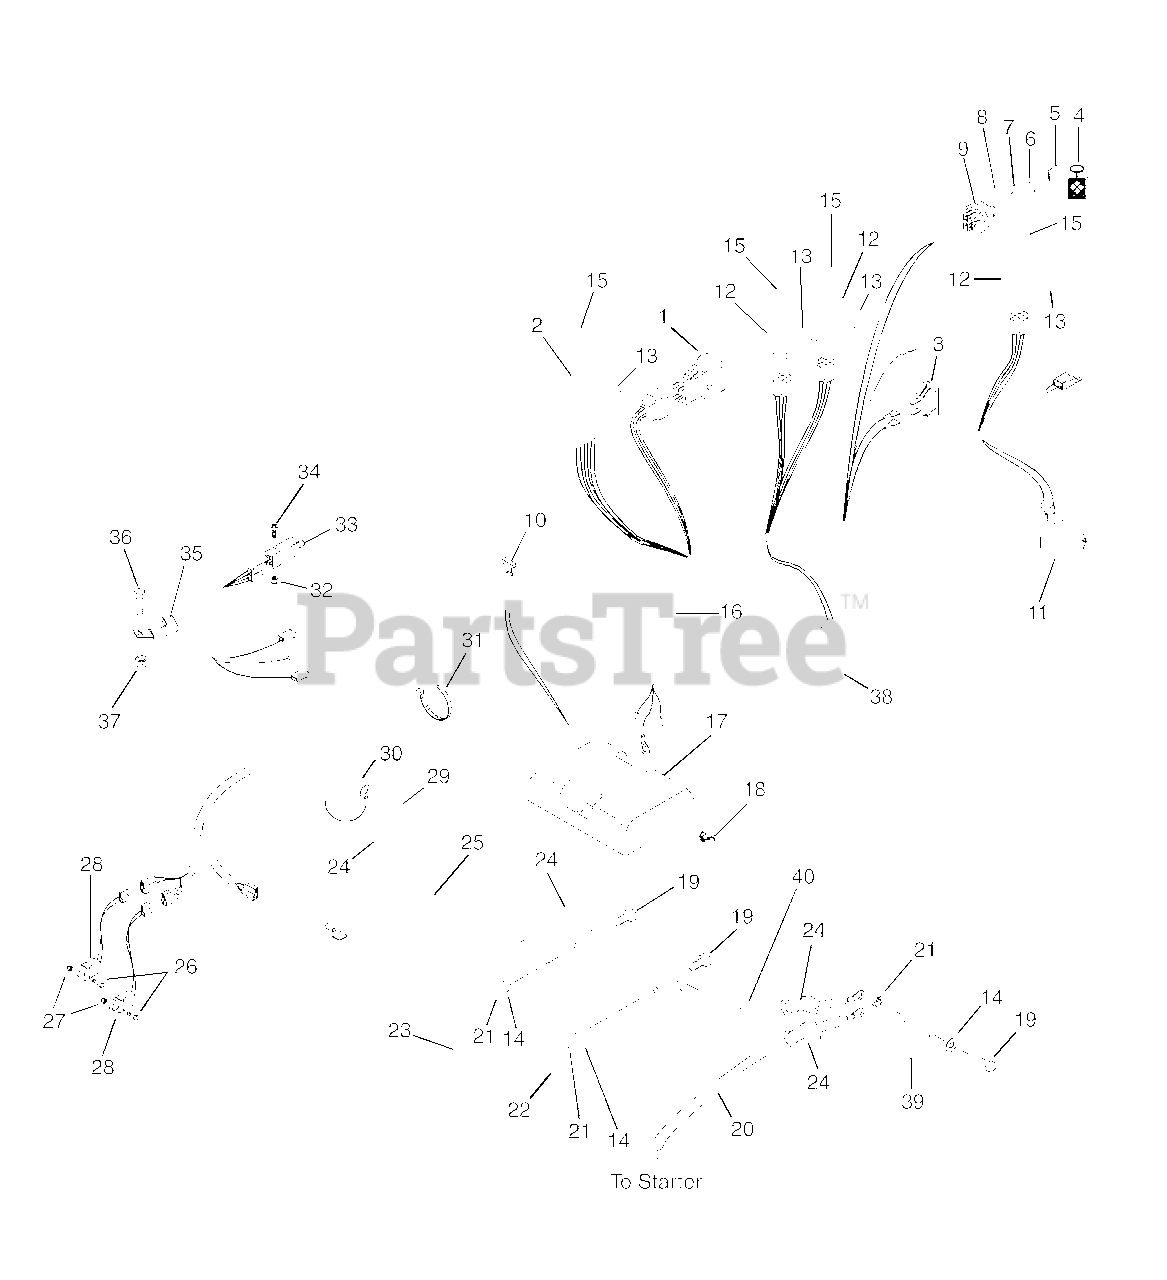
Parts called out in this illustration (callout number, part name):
1	Switch-Clutch with Retainer Ring
2	Module, Time Delay
3	Light-Indicator
4	Key Chain
5	Ignition Switch Key
6	Cap-Ignition Switch
7	Nut-Panel .562-24
8	Washer-Lock-Internal .563 x .040
9	Key Switch
10	Fuse, 30 Amp
11	Hour Meter
12	Relay
13	Screw-Machine 10-24 x .75 Hex Washer Head
14	Washer-Flat-Steel .281 x .620 x .065
15	Retainer Nut 10-24
16	Harness-Wiring
17	Cover-Battery
18	Nut-Locking-Wing .250-20
19	Bolt-Hex .25-20 x .75 Grade 5
20	Cable-Starter
21	Nut-Hex .25-20
23	Rod-Battery
24	Boot-Insulator
25	Cable-Negative Battery
26	Screw-Machine 6-32 x .75
27	Nut-Locking-Nylon 6-32 w/Insert
28	Switch
29	Bolt-Hex .31-18 x 1.00 Grade 5
30	Nut-Locking-Center .31-18
31	Tie-Wrap-Black
32	Nut-Locking-Nylon 10-24 w/Insert
33	Switch-Single Pole N.O.
34	Screw-Machine .38-7.0
36	Bolt-Hex .38-16 x 1.00 Grade 5
37	Nut-Locking-Center .38-16
38	Molded Diode Plug
39	Solenoid
40	Cable, Battery to Solenoid
